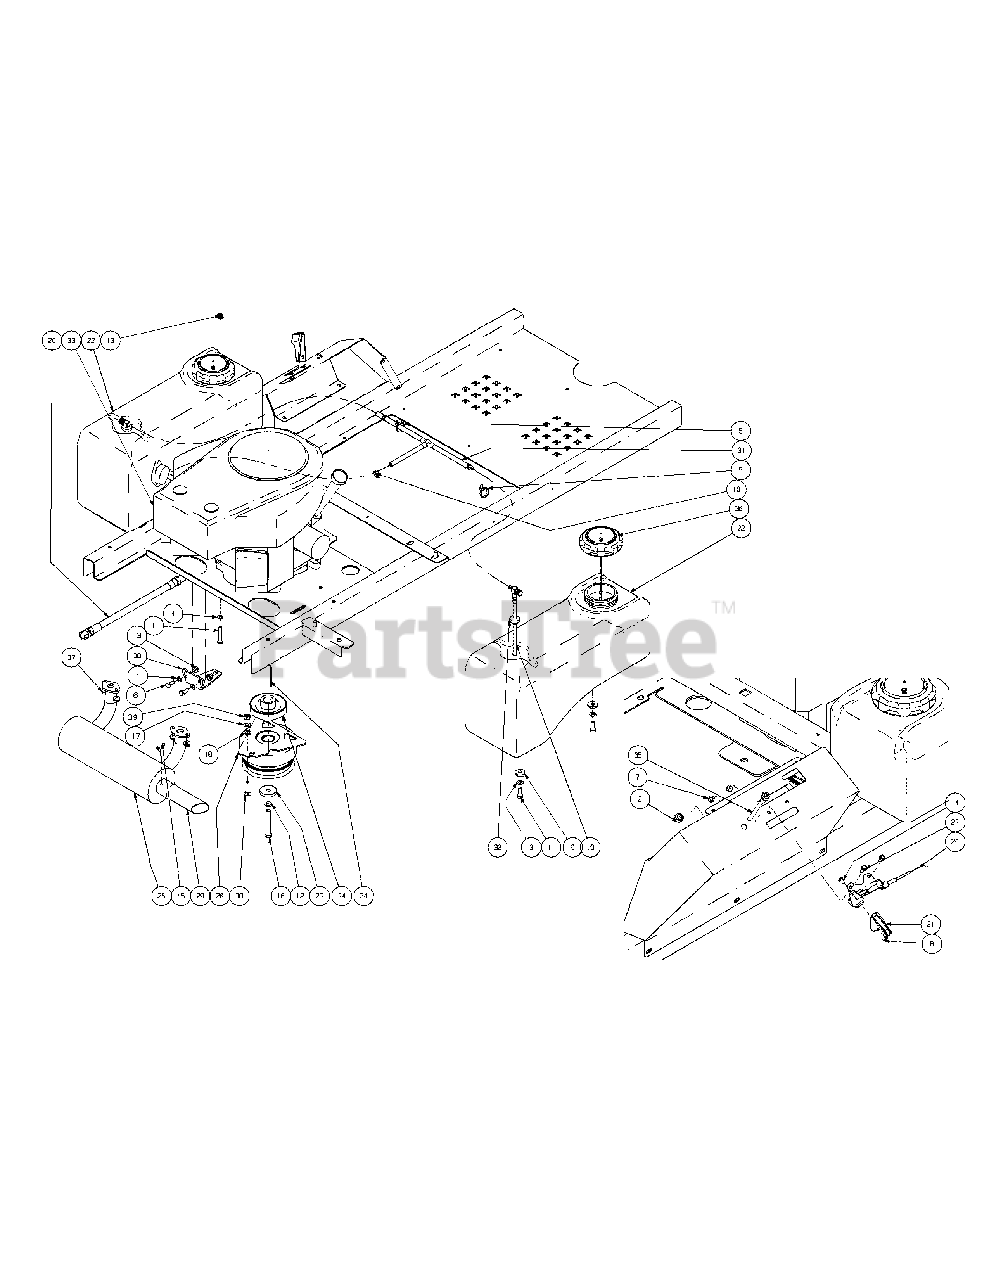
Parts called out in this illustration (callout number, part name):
1	HHCS, 5/16-18, 1-3/4
2	Jam Nut, 3/8-24
3	Lock Washer, 3/8 Zinc
4	Flat Washer, 5/16
5	Cable Tie, 3/16 x .05 x 7.4
6	Hex Cap Screw, 5/16-18 x .75
7	Lock Nut, Nylon Insert, 10-32
8	Nut, w/ Star Washer
9	Flat Washer, .390 x 1.00 x .180
10	Hose Clamp, SAE #4: 1/4-5/8, SS
11	Hex Cap Screw, 3/8-16 x .88
12	Lock Washer, 7/16
13	Lock Nut, Hex Flange, 5/16-18
14	Machine Screw, 8-32 x .375
15	Screw, 8-32 x .375, Hex Washer
16	Hex Cap Screw, 7/16-20 x 3.0
17	Lock Washer, 5/16
18	Washer, 3/8 x .738 x .063
19	Fuel Pickup Fitting
20	Oil Drain Extension Hose
21	Throttle Control Knob
22	Fuel Tank
23	Flat Washer, 7/16 ID x 1.75 OD x .250
24	Key, 1/4 x 1/4 x 2.75
25	Kawasaki Muffler
26	Ogura DX11 Electric Clutch
27	Screw, #10-32 x 0.500
28	Exhaust Pipe
29	Throttle Control Cable
30	Clutch Retainer Assembly
31	Fuel Hose Assembly includes:
31	Hose, 1/4" Fuel Line (70 inches)
32	Fuel Tank Groment
33	19HP Kawasaki Engine
34	Transmission Drive Pulley
35	Choke Cable
37	Nut, M8-1.25, Hex Flange
38	Carriage Bolt, 5/16-18 x 1.75
39	Hex Nut, 5/16-18
